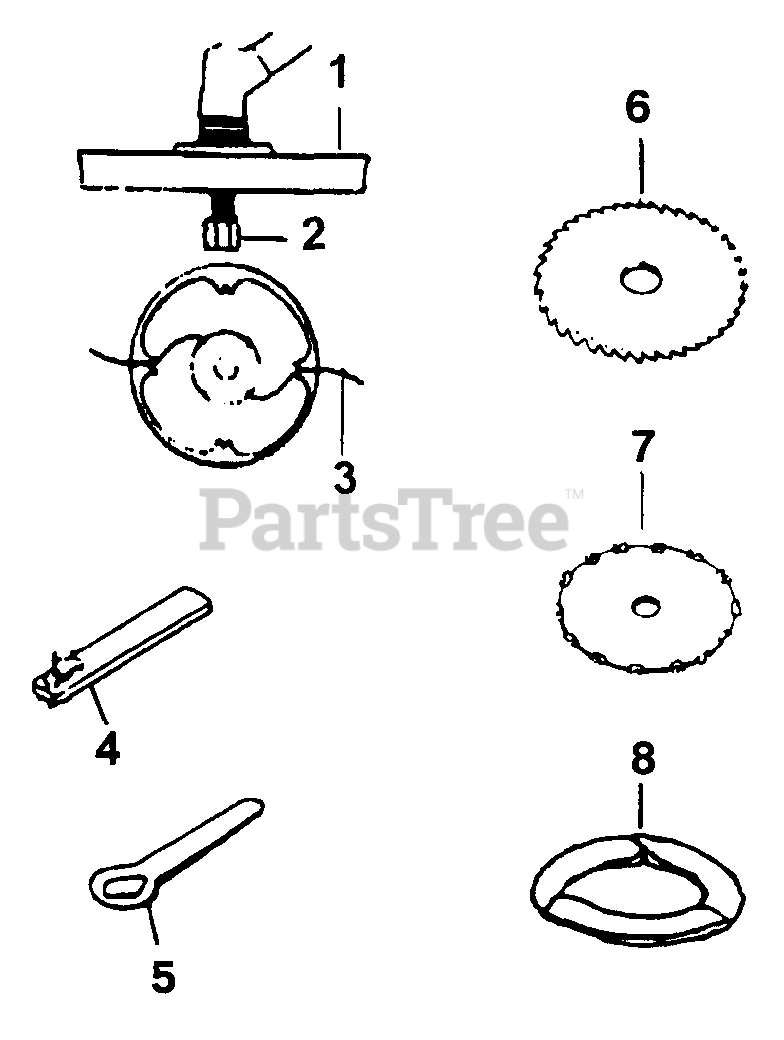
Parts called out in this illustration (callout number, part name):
1	Fixed Line Head
2	Arbor Bolt
3	Green Line .105 X 20"
4	Rotor Puller
5	Pusher, Piston Pin
6	Flywheel Holder
7	Saw Blade
8	XRT Blade
9	Cover, Blade
